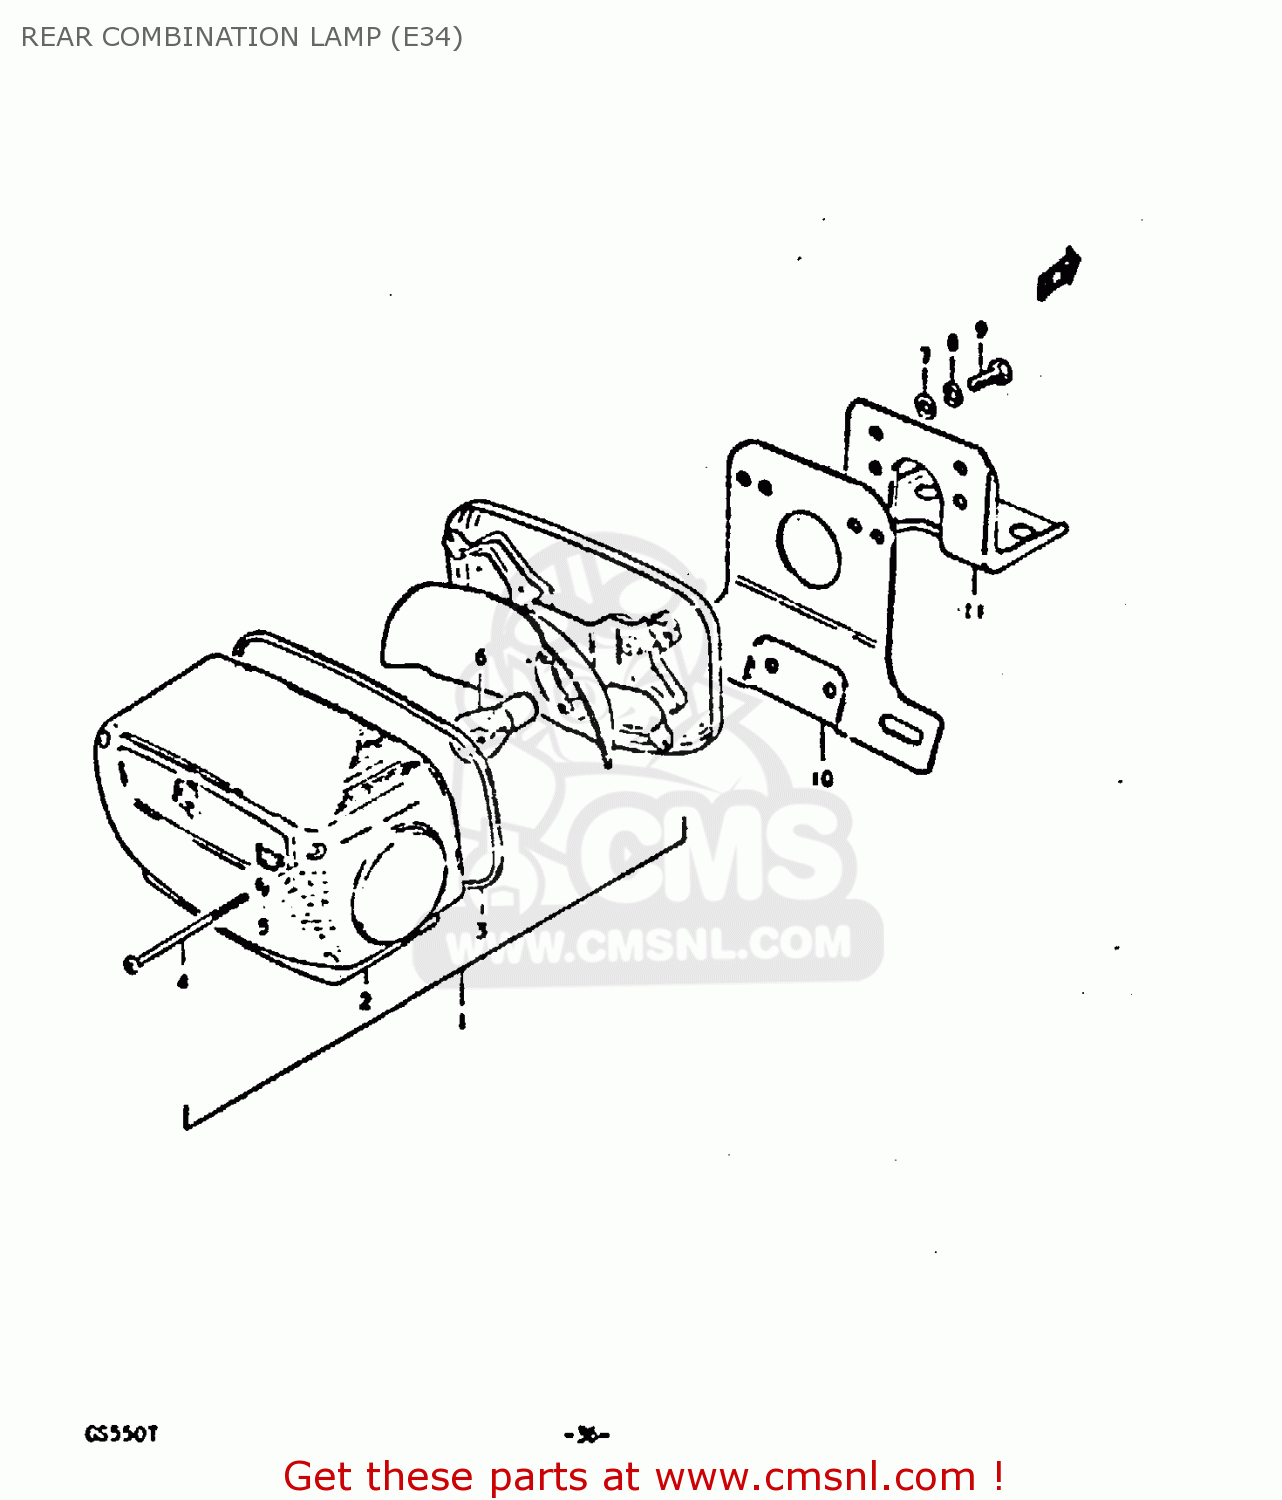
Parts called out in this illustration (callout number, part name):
1	LAMP ASSY, REAR COMBINATION
2	LENS
3	GASKET (NAS)
4	SCREW (4X55)
5	GASKET (NAS)
6	BULB(12V21/5W)
7	WASHER
8	LOCK WASHER
9	BOLT
10	PLATE, LICENCE
11	BRACKET,LICENSE PLATE
